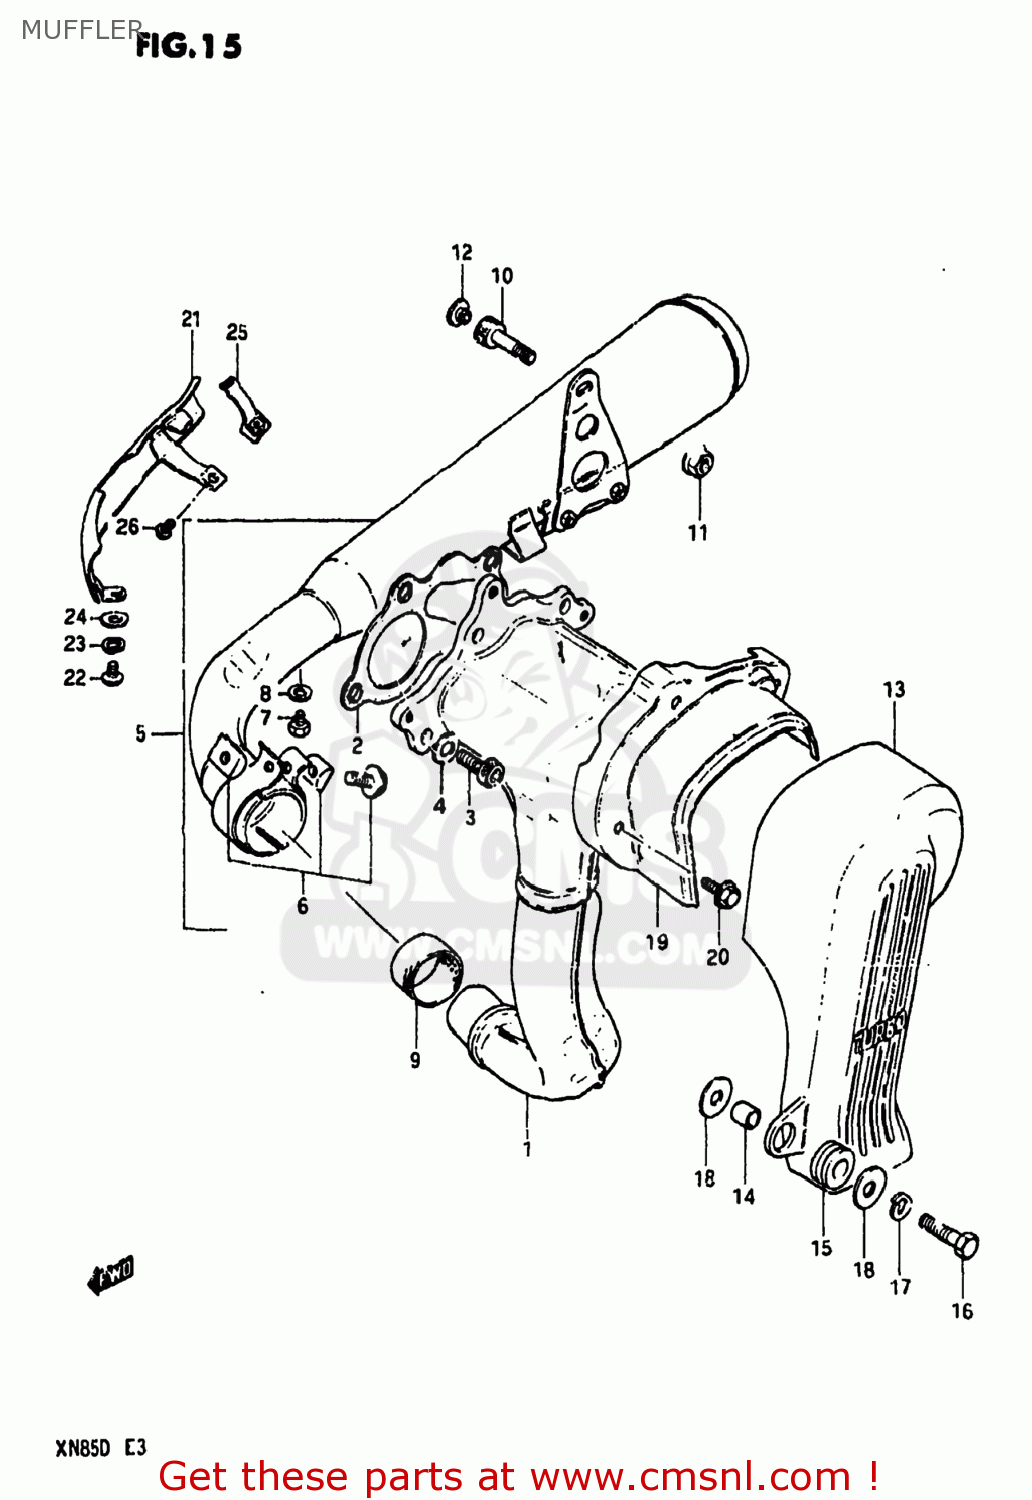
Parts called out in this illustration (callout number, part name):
1	PIPE,MUFFLER
2	GASKET,TURBO OUT
3	BOLT(8X20)
4	WASHER
5	MUFFLER ASSEMBLY
6	PLATE SET,MUFFLER
7	BOLT
8	WASHER
9	CONNECTOR,MUFFLER
10	BOLT
11	NUT
12	CAP
13	COVER,MUFFLER NO.1
14	SPACER (8.8X12X11)
15	CUSHION
16	BOLT
17	LOCK WASHER
18	WASHER (8.5X20X1.6)
19	COVER, INNER
20	BOLT
21	COVER,MUFFLER
22	SCREW
23	LOCK WASHER
24	WASHER
25	CLAMP,MUFFLER COVER
26	SCREW
